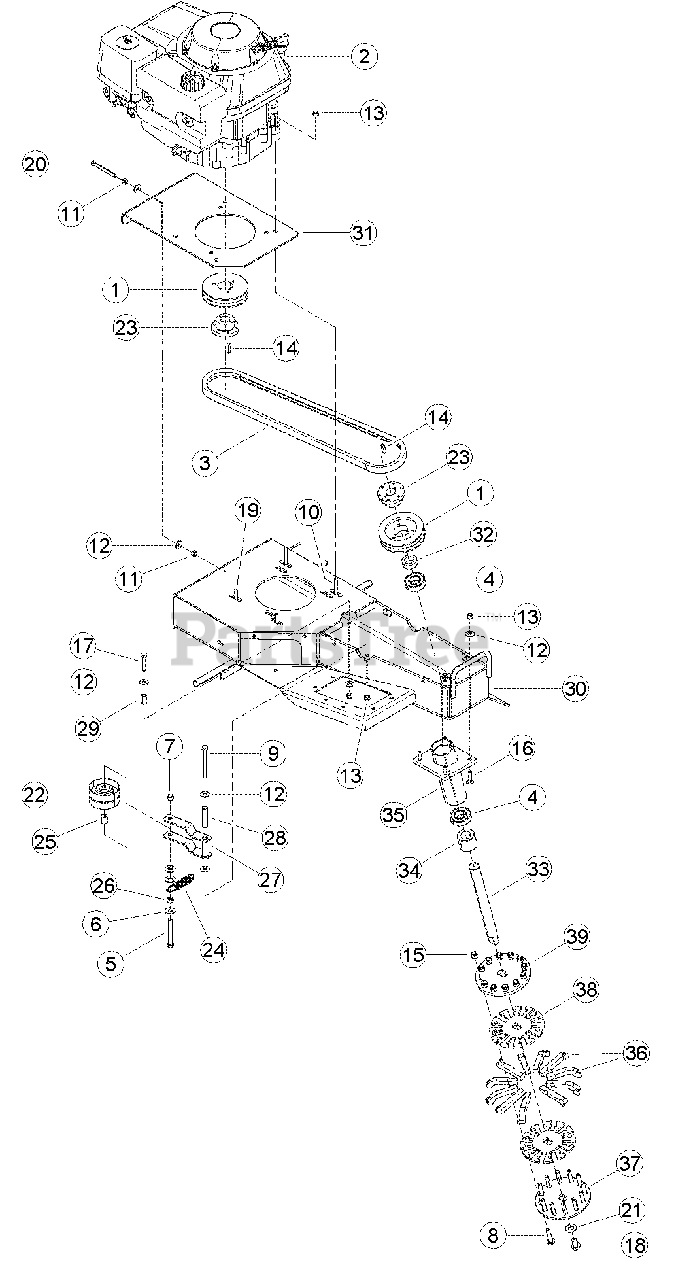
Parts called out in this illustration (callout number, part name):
1	SHEAVE, 3V4.5-2 GROOVE SH
2	ENGINE, 11 HP HONDA GXV (FOR SERVICE SEE OWNER'S MANUAL OR YOUR NEAREST AUTHORIZED HONDA ENGINE DEALER)
3	BELT, 3VX530 DOUBLE BANDED
4	BEARING, 1 IN. BALL
5	BOLT, 3/8 X 3 HEX HD GR5 ZP
6	WASHER, 3/8 FLAT ZP
7	NUT, 3/8 CENTERLOCK ZP
8	BOLT, 3/8 X 1-3/4 CRG GR5 ZP
9	BOLT, 5/16 X 3-1/2 HEX HD ZP
10	BOLT, 5/16 X 2 HCS GR5 ZP
11	NUT, 5/16 HEX NC ZP
12	WASHER, 5/16 FLAT ZP
13	NUT, 5/16 NE NYLOCK ZP
14	KEY, 1/4 SQUARE X 1 LONG
15	NUT, 3/8 NE NYLOCK ZP
16	BOLT, 5/16 X 1-1/4 CRG GR5 ZP
17	BOLT, 5/16-18 X 1-3/4 HCS GR5 ZP
18	BOLT, 1/2-20 X 3/4 HEX HD GR5 NF ZP
19	BOLT, 5/16 X 1-1/4 HCS NF GR5 ZP
20	SCREW, 5/16 X 3 SQ HD SET
21	WASHER, 1/2 HI-STRENGTH SAE ZP
22	PULLEY, 3-1/4 FLAT IDLER
23	BUSHING, SH 1"
24	SPRING, 3/4"OD EXTENSION
25	TUBE, SPACER 3/4" LONG IDLER
26	SPACER IDLER PIVOT
27	WELDMENT, 2 BELT IDLER
28	PIVOT TUBE
29	SPACER, .54 X .88
30	WELDMENT, STUMPGRINDER FRAME
31	PLATE, ENGINE SLIDE
32	SPACER, 1-1/2 X 1/2
33	SPINDLE, CUTTER SG 12 BLADE
34	TUBE, SPACER 1-3/4 X 1.520
35	WELDMENT, SPINDLE HUB
36	KIT, 12 BLADE CUTTER REPLACEMENT
37	PLATE, COVER STUMPGRINDER HEAD
38	PLATE, SPACER STUMPGRINDER HEAD
39	PLATE, DISK STUMPGRINDER HEAD
